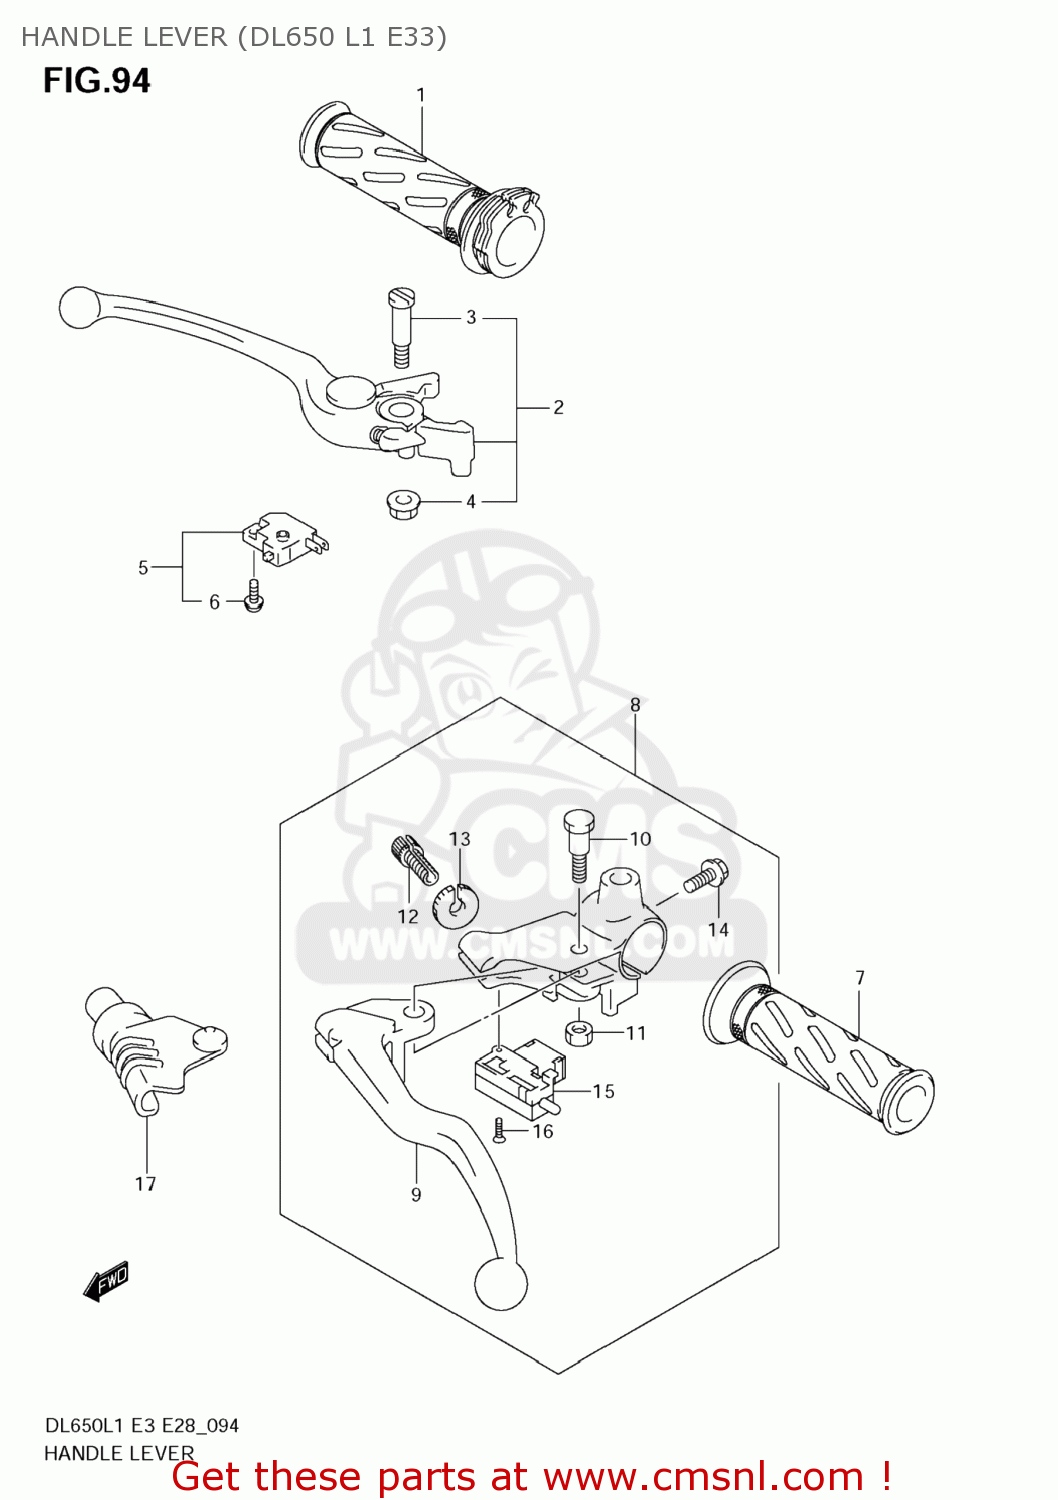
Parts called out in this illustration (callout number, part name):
1	GRIP,THROTTLE(BLACK)
2	LEVER ASSY,FR
3	BOLT,LEVER PIV
4	NUT
5	SWITCH ASSY,ST
6	SCREW
7	GRIP,L
8	LEVER ASSY,CLUTCH
9	LEVER,CLUTCH
10	BOLT,LEVER PIVOT
11	NUT
12	ADJUSTER,WIRE
13	NUT,LOCK
14	BOLT
15	SWITCH ASSY,CLUTCH
16	SCREW
17	COVER,CLUTCH LEVER
